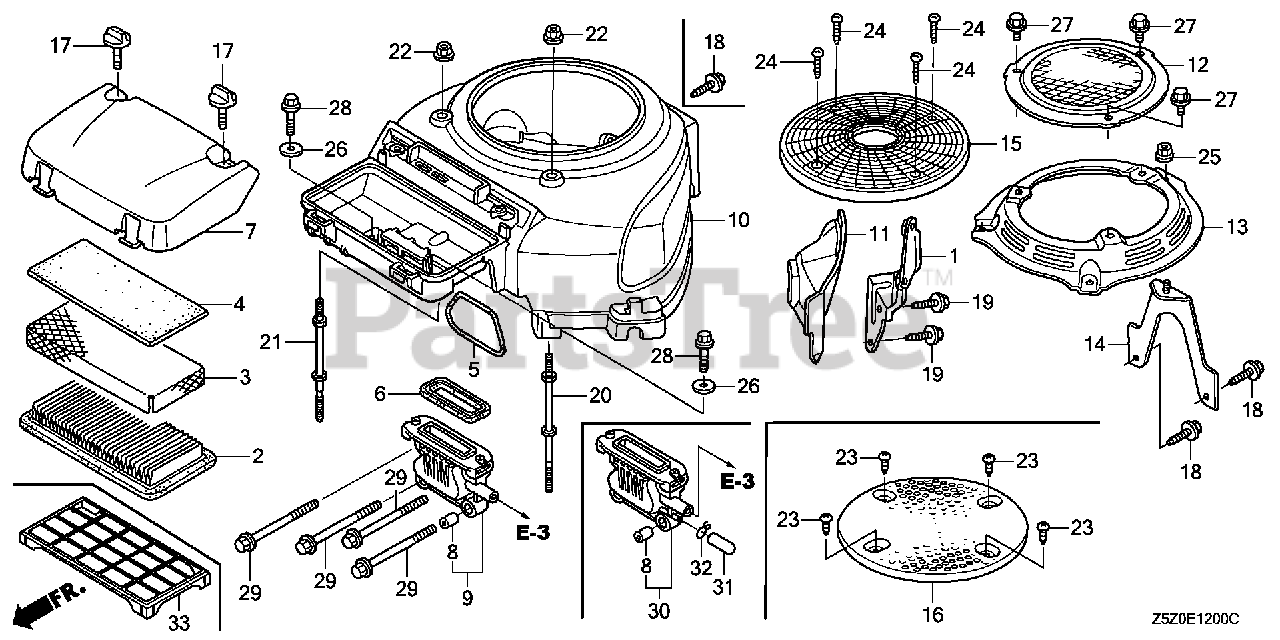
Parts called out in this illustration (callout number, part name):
2	ELEMENT, AIR CLEANER
3	GRID, AIR CLEANER
4	FILTER (OUTER)
5	GASKET, AIR CLEANER
6	SEAL, AIR CLEANER HOUSING
7	COVER, AIR CLEANER
8	COLLAR A, AIR CLEANER
9	ELBOW, AIR CLEANER
10	COVER, FAN *NH1* (BLACK)
10	COVER, FAN *R280* (POWER RED)
11	PLATE, SIDE
15	GRID, SCREEN (D50) *NH1* (BLACK)
15	GRID, SCREEN (D50) *R280* (POWER RED)
17	BOLT, AIR CLEANER (6MM)
18	BOLT, FLANGE (6X14) (CT200)
19	BOLT, FLANGE (6X14)
20	BOLT, L. STUD (IGNITION COIL)
21	BOLT, R. STUD (IGNITION COIL)
22	NUT, FLANGE (6MM)
24	SCREW, TAPPING (4X30) (PO)
26	WASHER, PLAIN (6MM)
28	BOLT, FLANGE (6X12) Use up to Engine SN 1543277.
29	BOLT, FLANGE (6X100)
30	ELBOW, AIR CLEANER
31	CAP, SEALING
32	CLIP, TUBE (B10)
33	GRID, AIR CLEANER
